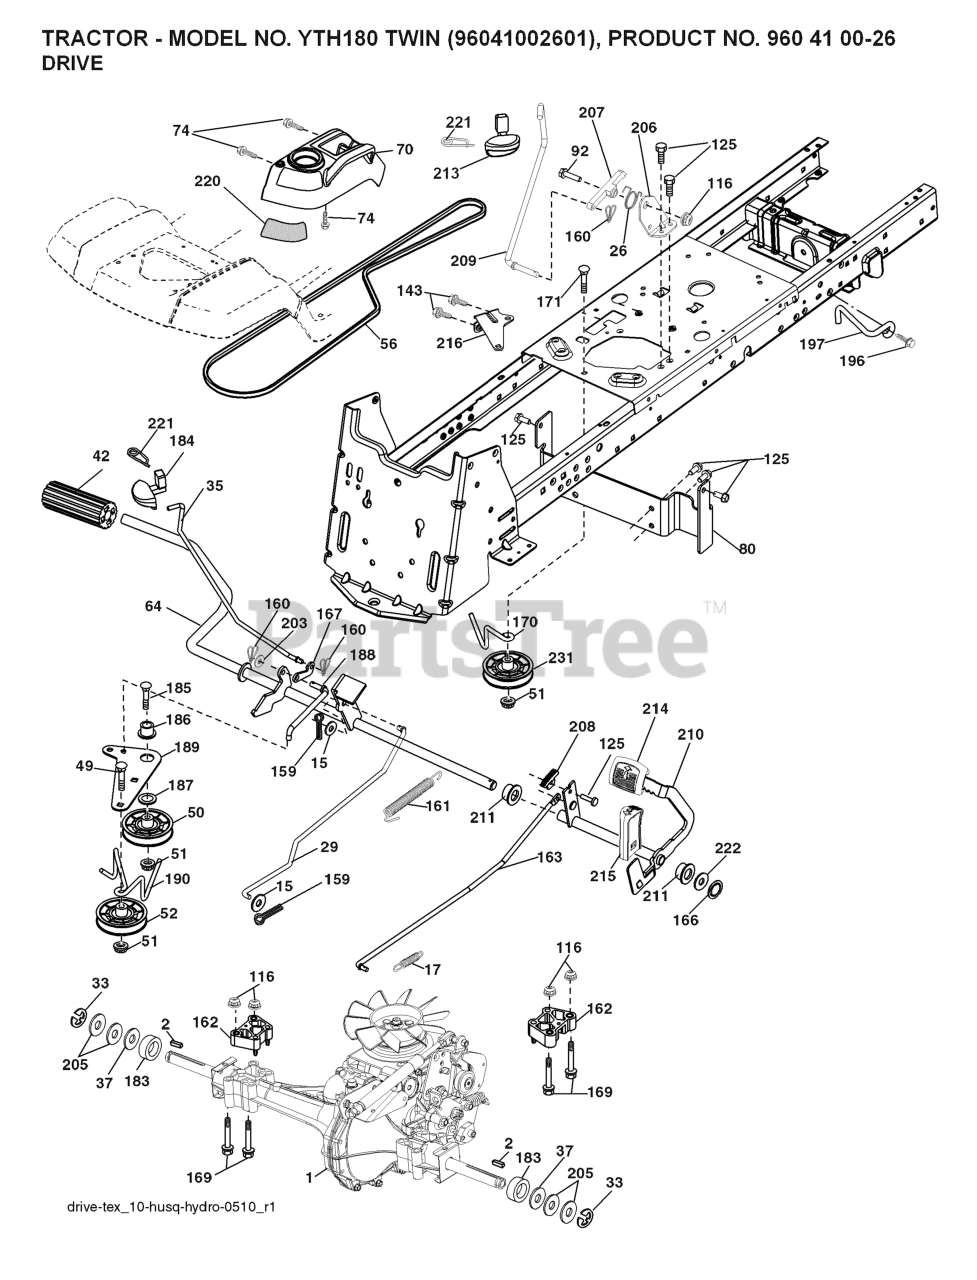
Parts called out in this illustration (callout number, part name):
2	SQUARE KEY
15	WASHER
17	SPRING.BRAKE.HG3000/3500
26	SPRING.RETURN.CRUISE
29	ROD.BRAKE.0610.PEDAL.CONTROL
35	ROD.BRAKE.PARKING.GT.H
42	PEDAL COVER T
50	IDLER.FLAT.910.OFFSET
51	NUT LOCK FLG 3/8-16 UNC
52	IDLER.V-GROOVE.910.OFFSET
64	SHAFT.ASM.PEDAL.BRK.CNTR
70	RP CONSOLE.ASM.PCH.W/TB
74	SCREW.HI-LO.CONSOLE
80	BRKT.STRP.TRQ.LT.HYD.C
92	BOLT
116	NUT LOCK HEX FLANGE 5/16-18
125	SCREW
143	Screw 5/16-18 x 1/2 Hex, Self Tapping 5/16-18 x 1/2
153	RETAINER M
159	COTTER PIN
160	RETAINER CLIP
161	SPRING.RETURN.CLUTCH.2006
162	SPACER.TRANSAXLE.18&22
163	ROD.PEDAL.CONTROL.0510
166	NUT.PUSH.625.2006
167	LATCH.BRAKE.SPRING
169	BOLT.HEX.FLNG.5/16-18X3.75
170	KEEPER.V-IDLER.CENTER.
183	SPACER AXLE
184	HANDLE.PARKG.BRK.HUSQ X667
186	SPACER.RETAINER
187	WASHER 12/32X2X10GA
188	RP.LINK.CLUTCH.GROUND.DRIVE
189	BELLCRANK.GROUND.DRIVE.TEX.
190	KEEPER.BELLCRANK.DRIVE
196	SCREW 3/8-16X1
197	LINK.CLUTCH.ANIT-ROTAT
203	WASHER
206	BRKT.MOUNT.LATCH.CRUIS
207	LATCH.CONTROL.CRUISE
208	GEAR.SECTOR.CONTROL.CR
209	ROD.CONTROL.CRUISE.GT.
210	ROCKER.ASM.PEDAL.CONTR
211	BEARING.NYLON
213	KNOB.CONTROL.CRUSIE.HU
214	PEDAL.FORWARD.TEX.GT.4
215	PEDAL.REVERSE.TEX.GT.4
216	BRACKET.PULLEY.IDLER.W/TEX
220	REFLECTOR.RH.TEX GT
221	RETAINER.SPRING.CLIP.H
222	WASHER
231	IDLER.V-GROOVE.1.688.OFFSET
